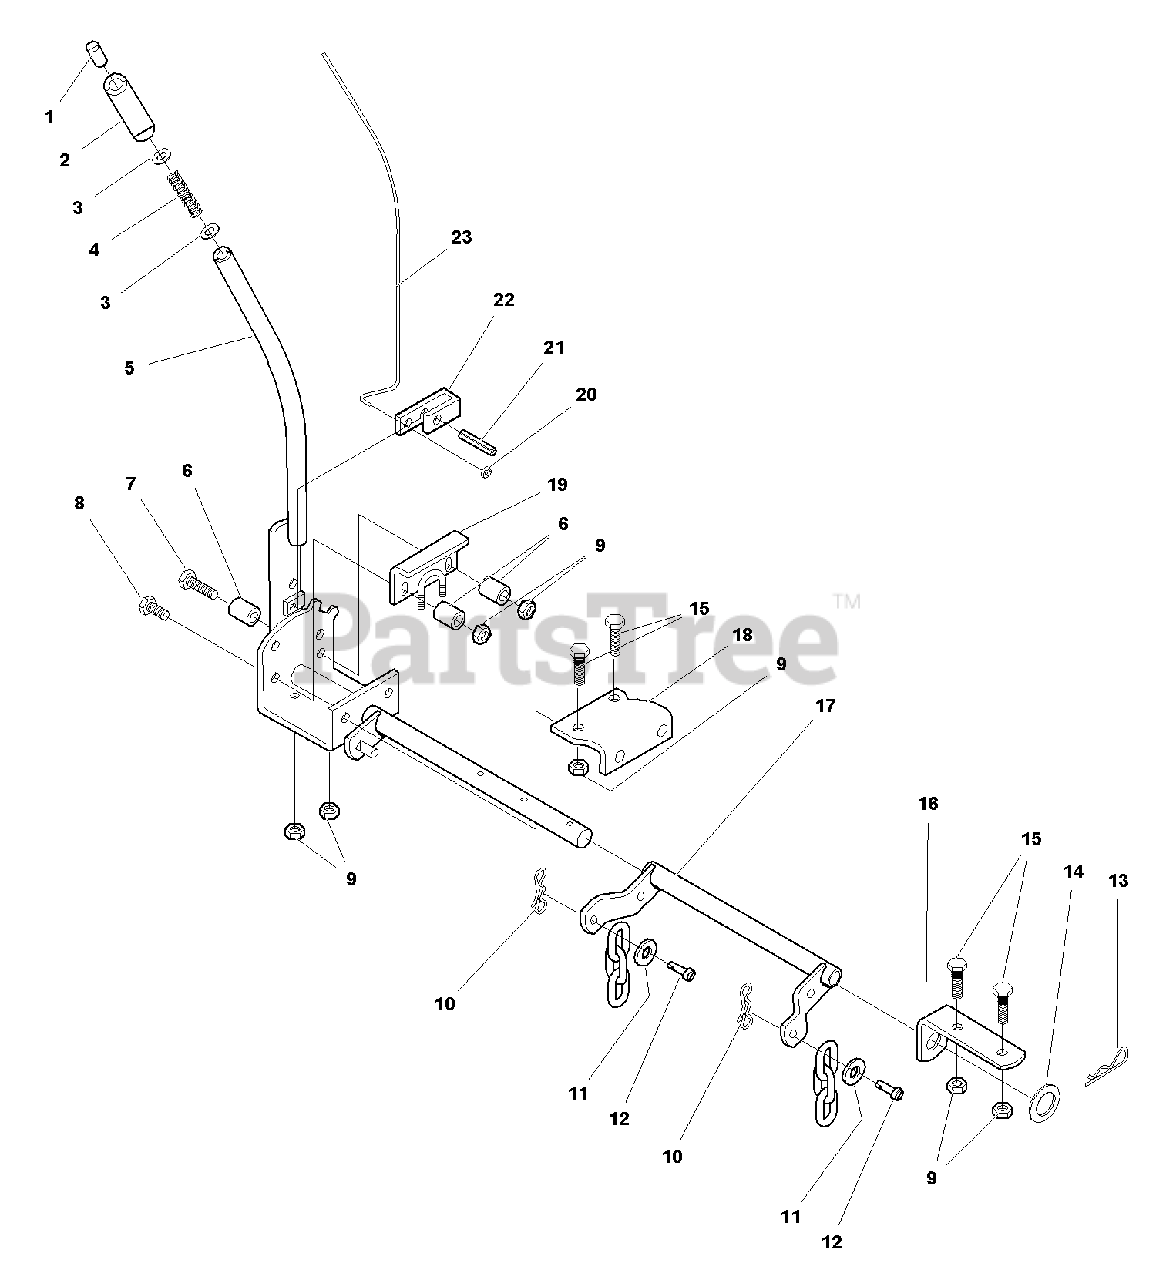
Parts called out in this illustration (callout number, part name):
3	WASHER, 5/16
4	SPRING, Compression
5	QUADRANT & LEVER ASSEMBLY
7	CAPSCREW, Hex Head, 5/16-18 x 1-3/4
8	CAPSCREW, Hex Head, 5/16-18 x 1-1/4
9	LOCKNUT, ESNA, 5/16-18
10	PIN, Cotter Locking
11	WASHER, 3/8
12	PIN, Round Head, Drilled, 3/8 x 1
13	HAIR PIN, Clip
14	WASHER, 3/4
15	CAPSCREW, Hex Head, 5/16-18 x 7/8
17	TUBE & ARMS ASSEMBLY
18	BRACKET & PINS ASSEMBLY
19	BRACKET & U BOLT ASSEMBLY (Early Models)
19	BRACKET & U BOLT ASSEMBLY (Later Models)
20	PUSH NUT, 5/16
21	ROLL PIN, 3/8 x 1
22	LATCH
